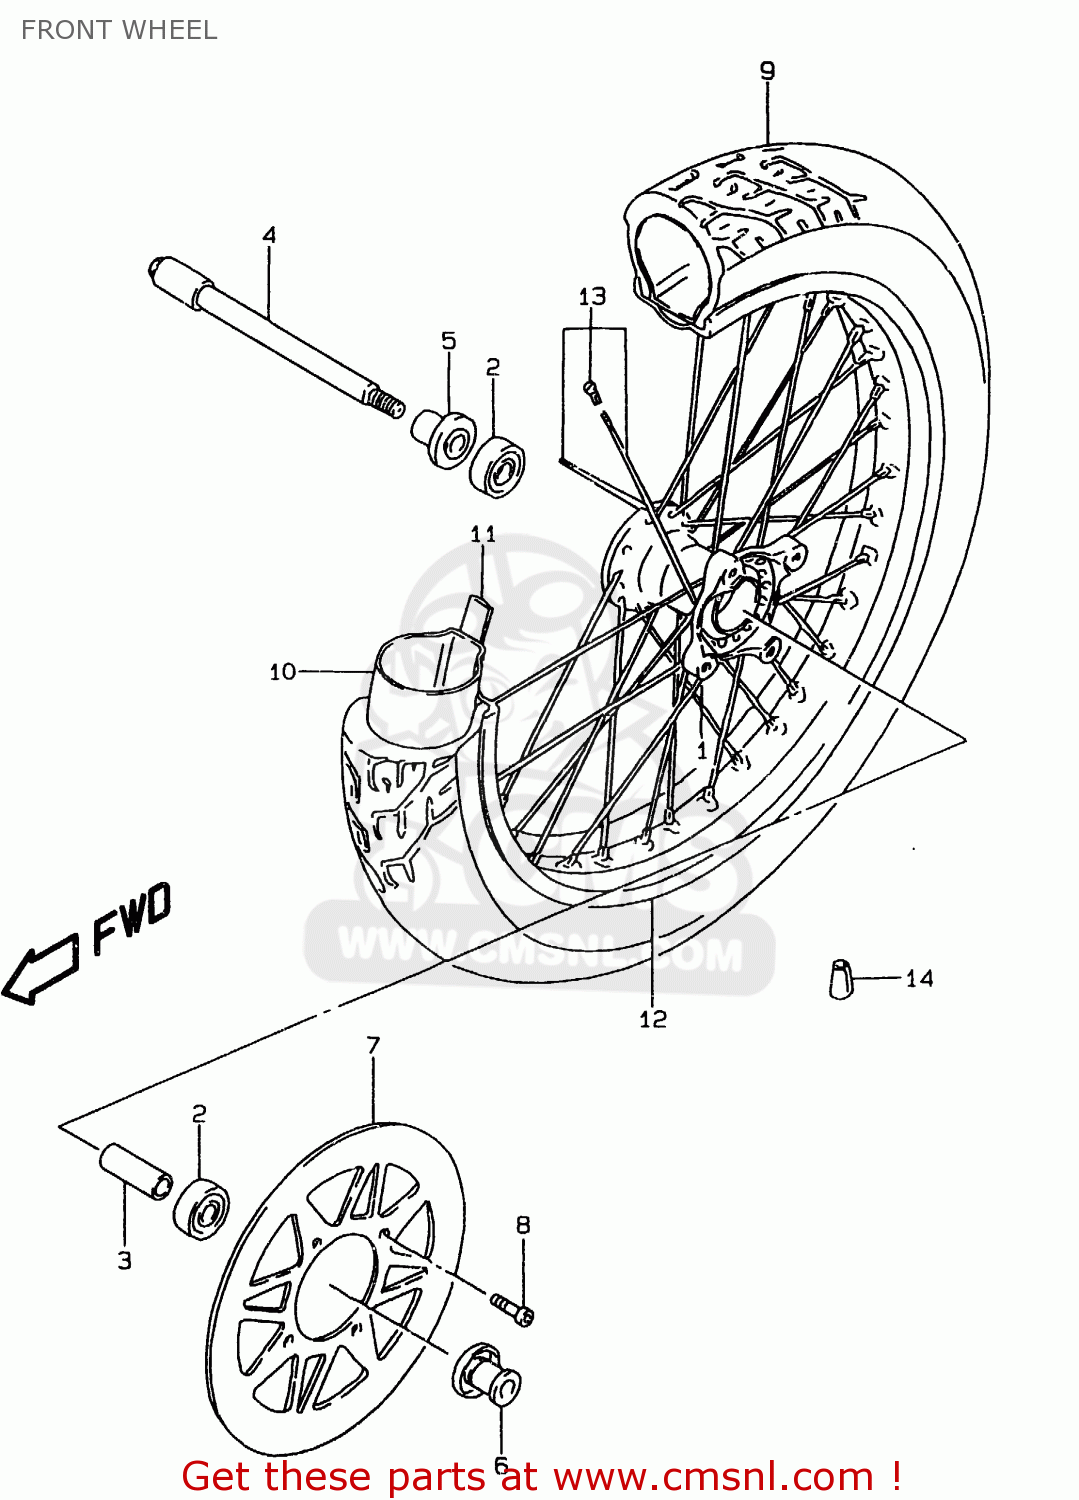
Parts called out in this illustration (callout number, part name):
1	HUB,FR WHEEL
2	BEARING
3	SPACER(15.3X21.7X56)
4	AXLE,FR
5	SPACER,FR AXLE,R
6	SPACER,FR AXLE,L
7	DISC,FR BRAKE
8	BOLT(8X25.5)
9	TIRE,FR(100/90-19 57H)
10	TUBE
11	PROTECTOR,WHL INR TUBE
12	RIM,FR WHEEL WM(2.15X19)
13	SPOKE SET,FRONT
14	BALANCER,WHEEL
